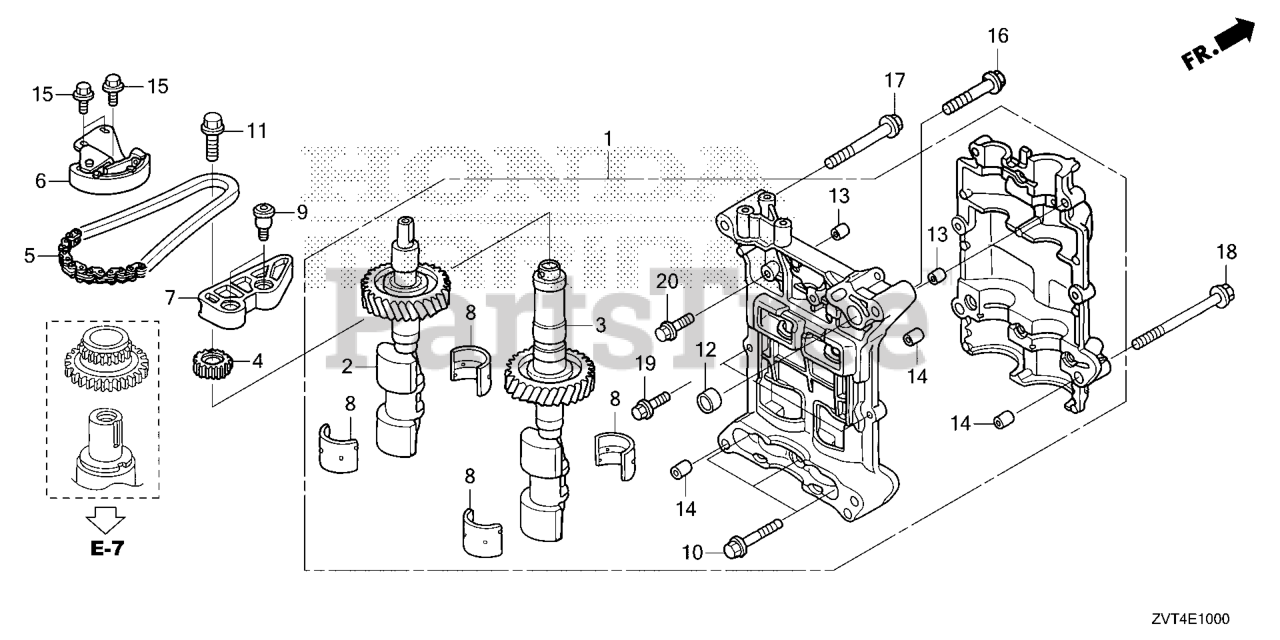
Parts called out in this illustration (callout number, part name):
1	CASE ASSY., BALANCER HOLDER
2	SHAFT, FR. BALANCER
3	SHAFT, RR. BALANCER
4	SPROCKET, DRIVEN (17T)
5	CHAIN (62L)
6	TENSIONER, BALANCER SHAFT CHAIN
7	GUIDE, BALANCER SHAFT CHAIN
8	METAL, BALANCER SHAFT (DAIDO)
9	BOLT, CHAIN GUIDE
10	BOLT, FLANGE (8X55)
11	BOLT-WASHER (10X30)
12	PIN, DOWEL (18X13)
13	PIN A, DOWEL (8X10)
14	PIN A, DOWEL (12X16)
15	BOLT, FLANGE (6X14)
16	BOLT, FLANGE (8X50)
17	BOLT, FLANGE (8X75)
18	BOLT, FLANGE (10X105)
19	BOLT, FLANGE (6X25)
20	BOLT, FLANGE (6X32)
